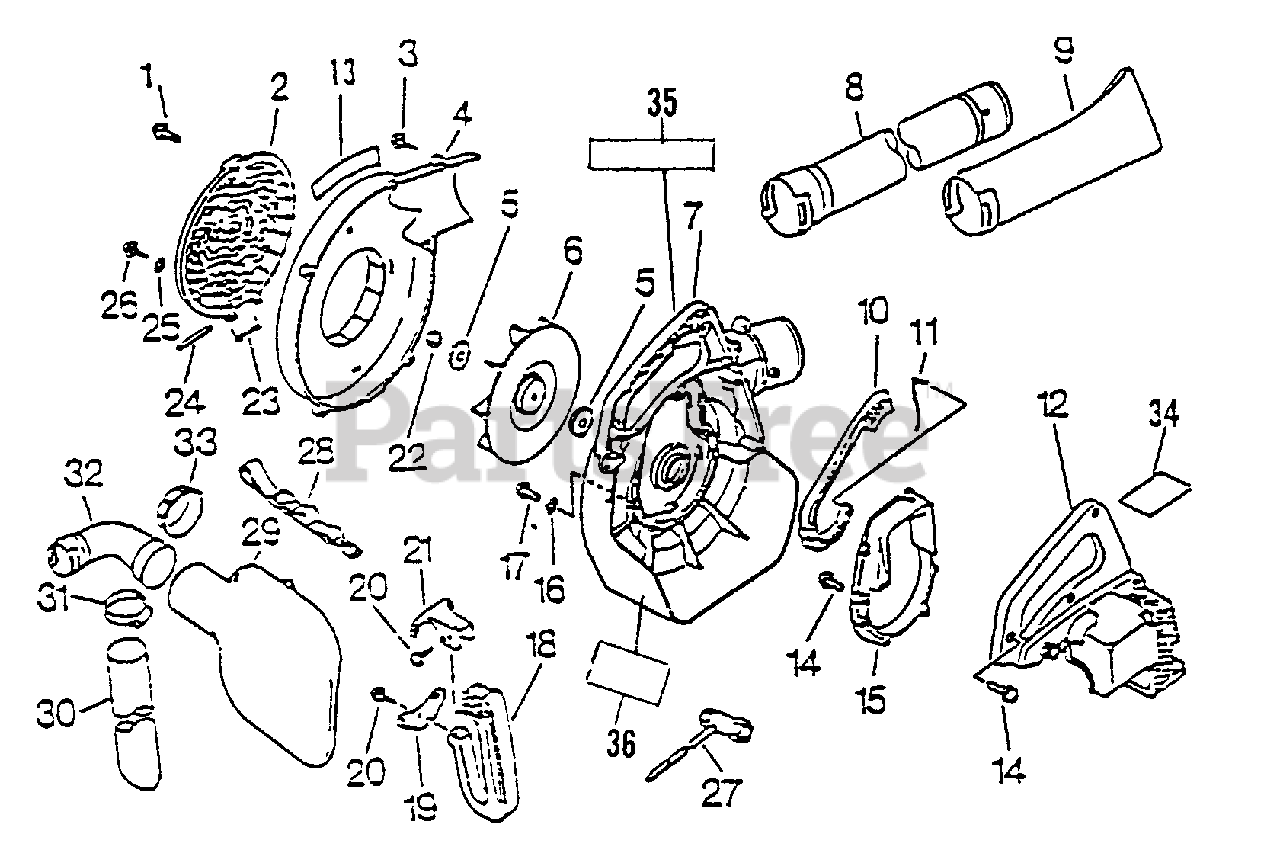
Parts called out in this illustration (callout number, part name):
1	SCREW 5×18
2	SHIELD, DEBRIS
3	SCREW, TAPPING 5×20
4	COVER, FAN - LEFT
6	FAN
7	COVER, FAN - RIGHT
8	TUBE, BLOWER - STRAIGHT
9	NOZZLE - FAN HEAD
10	TRIGGER, THROTTLE
11	ROD, THROTTLE
12	COVER, ENGINE
13	LABEL, MODEL
14	SCREW 4×18
15	BRACKET, ENGINE
17	SCREW 4×22
18	HANDLE
19	SUPPORTER, HANDLE
21	SUPPORTER, HANDLE
23	SPRING, COIL
24	PIN, INTAKE COVER
26	SCREW 5×14
27	T-WRENCH 13×19×180
28	HARNESS
30	ADAPTER, TUBE
32	CONNECTOR
33	RING
34	LABEL - CAUTION -- HOT
35	LABEL - NOISE
36	LABEL - CAUTION
